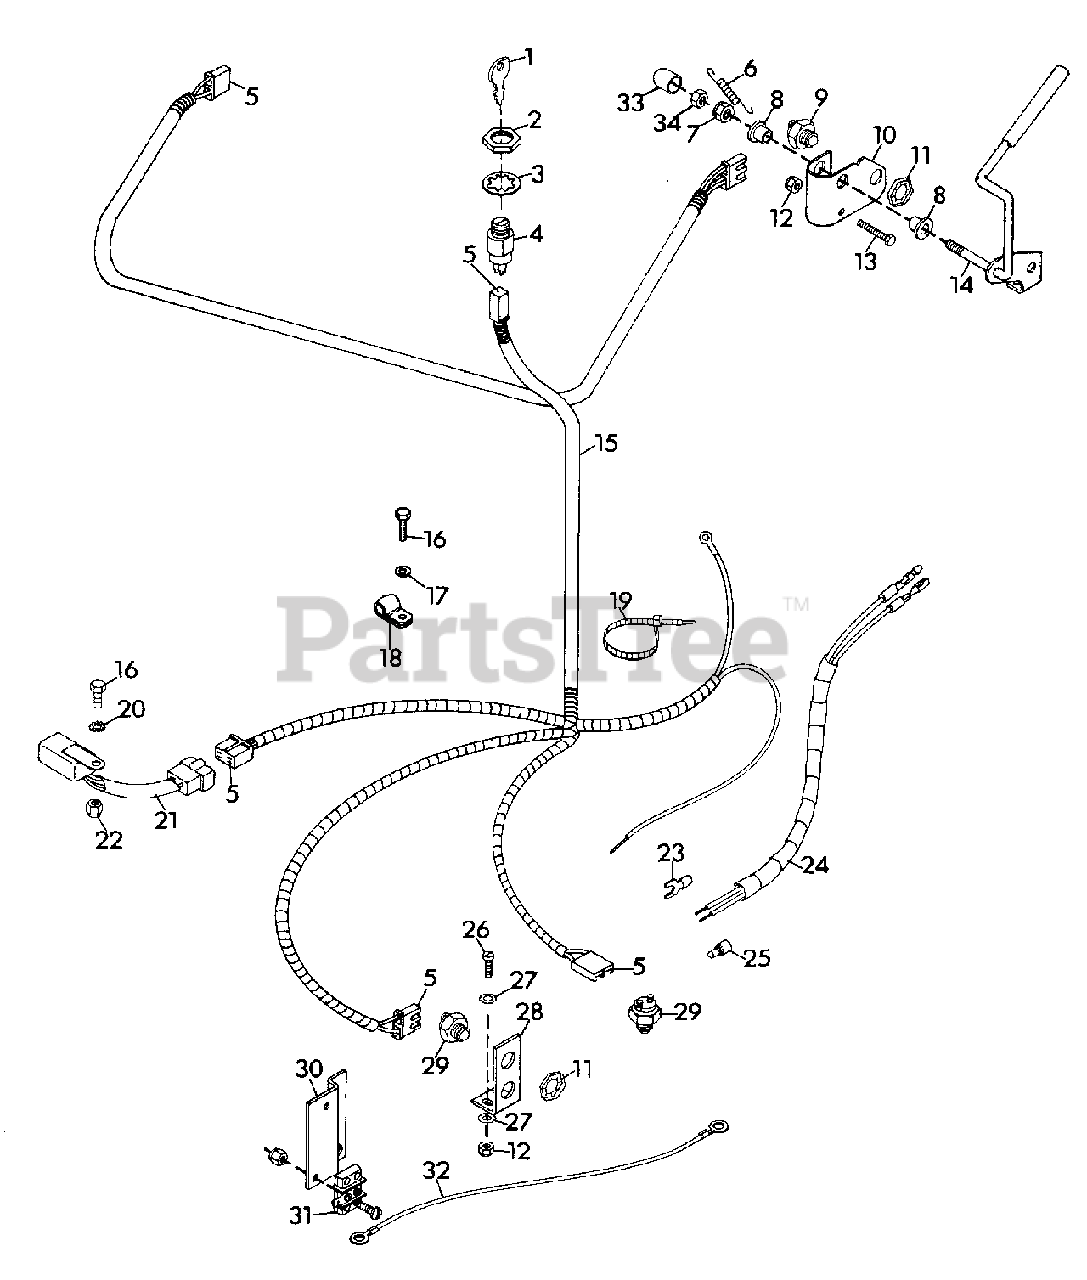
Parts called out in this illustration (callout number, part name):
1	KEY, IGNITION SWITCH
2	NUT, JAM 5/8-32
3	WASHER, LOCK 5/8 INT. TOOTH
4	SWITCH
5	TERMINAL
6	SPRING, INTERLOCK LEVER
7	NUT, LOCK 5/16-18
8	BUSHING, INTERLOCK LEVER
9	SWITCH, INTERLOCK
10	BRACKET, INTERLOCK ACTUATING
11	NUT, STAMPED 9/16-18
12	NUT, LOCK 10-24
13	SCREW, MACH. 10-24X1.50 PHD
14	LEVER, PRESENCE CONTROL
15	HARNESS
16	BOLT, HEX 1/4-20X.625
17	WASHER, FLAT .281X.625X.065
18	CLAMP
19	TIE, CABLE
20	WASHER, LOCK 1/4 EXT TH TYA
21	MODULE, INTERLOCK RECOIL
22	NUT, LOCK 1/4-20
24	WIRE, ENGINE KILL
25	NUT, WIRE
26	SCREW, MACHINE 10-24X.75 PHD
27	WASHER, FLAT .188X.438X.049
28	BRACKET, INTERLOCK SWITCH
29	SWITCH, NEUTRAL START
32	WIRE, GROUND
33	CLOSURE, VINYL
34	NUT, LOCK 5/16-18
